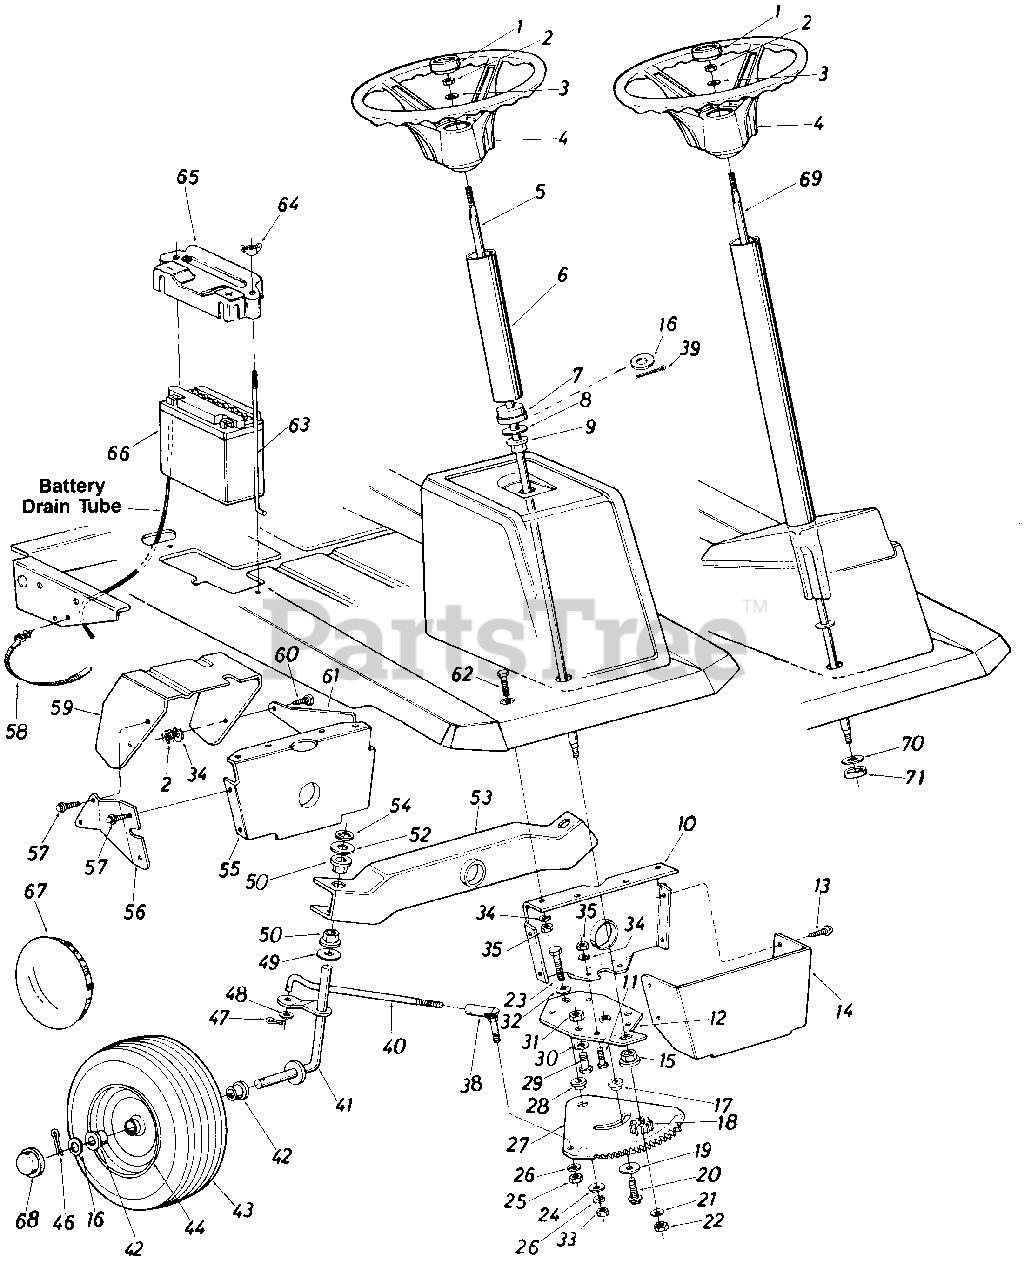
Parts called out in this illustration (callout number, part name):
1	Steering Wheel Cap
2	Hex Nut 5/16-18 Thd.
3	Bell-Wash. .345" I.D. x .88" O.D.
4	Steering Wheel Assy
5	Steering Shaft
8	Fl-Wash. .640" I.D. x 1.25" O.D.
9	Hex Flange Bearing
10	Pivot Bar Bracket
11	Hex Bolt 5/16-18 x .75" Lg.*
12	Steering Gear Support Brkt.
13	Hex Wash. Hd. AB-Tap Scr. 1/4 x.62" Lg.
16	Fl-Wash. .640" I.D. x 1.62" O D
17	Shoulder Spacer .622 Dia. x .218
18	Steering Pinion Gear
19	Fl-Vash. .385" I.D. x 1.38"
20	Hex Wash. Hd. Self-Tap Scr. 3/8-16 x 1.25" Lg.
21	Fl-Wash. .34" I.D. x .68" O. D.
22	Hex Nut 5/16-24 Thd.*
23	Hex Bolt 3/8-24 x 1.25" Lg. (Grade 5)
24	Fl-Wash. .385" I.D. x 1.38"
25	Hex Nut 3/8-24 Thd.*
26	L-Wash. 3/8" I.D.*
27	Steering Gear Segment
28	Shoulder Spacer .622" Dia. x .218
29	Hex Bolt (Nylon) 1/2-13 x .75"
30	Fl-Wash. .530" I.D. x .930"
31	Hex Nut 1/2-13 Thd.*
32	Bell-Wash. .385" I.D. x .88"
33	Hex Nut 3/8-24 Thd.*
34	L-Wash. 5/16" I.D.*
35	Hex Nut 5/16-18 Thd.*
38	Ball Joint Ass'y. 3/8-24 Thd.
39	Cotter Pin 118" Dia. x 1.00" Lg.*
40	Steering Tie Rod
41	Front Axle Ass'y.-R.H.
42	Flange Bearing .632" I.D.
43	Front Wheel Ass'y. Comp.
44	Front Wheel Rim Only
46	Cotter Pin 1/8" Dia. x 1.25"*
47	Cotter Pin 1/8" Dia. x 1.00"*
48	Fl-Wash. .385" I.D. x .87"
49	Fl-Wash. .635" I.D. x 1.12"
50	Hex Flange Bearing
52	Fl-Wash. .635" I.D. x 1.12"
53	Pivot Bar Ass'y.
54	Speed Nut 518" I.D.
55	Pivot Bar Bracket
56	Bracket Reinforcement-R.H.
57	Hex Wash. Hd. AB-Tap Scr. 1/4 x .62" Lg.
58	Cable Tie**
59	Clutch-Brake Pedal Ass'y.
60	Hex Bolt 5/16-18 x .75" Lg.*
61	Bracket Reinforcement-L.H.
62	Hex Bolt 5/16-18 x .75" Lg.*
63	Battery Hold Down Rod
64	Wing Nut Solid 1/4-20 Thd.
65	Battery Hold Down Cover
66	12V Battery
67	Chrome Hub Cap
68	Plastic Hub Cap
69	Steering Shaft Ass'y.
70	Fl-Wash. .62" I.D. x 1 50" O.D.
71	Spacer (Plastic)
